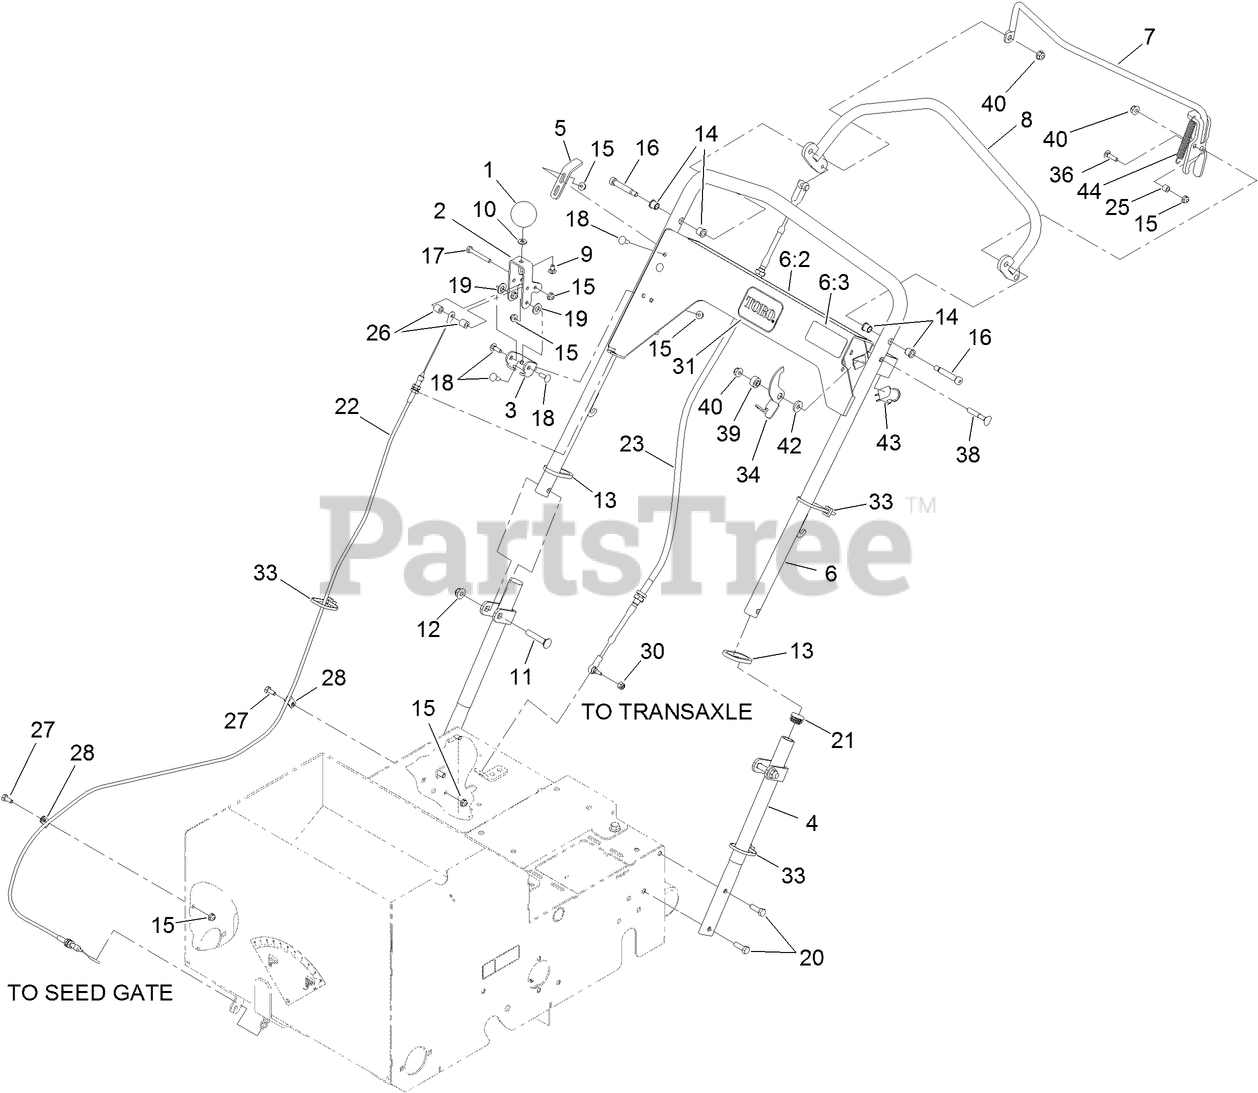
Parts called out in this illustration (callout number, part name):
1	KNOB-RATE, FLOW
2	LEVER-ADJUST, FLOW
3	BRACKET-ADJUST, FLOW
4	HANDLE-LOWER
5	BRACKET-ADJUST, DRIVE
6	HANDLE
6:2	DECAL-CONTROL PANEL, SEEDER
6:3	DECAL-SAFETY LATCH
8	HANDLE-DRIVE
9	SCREW-CARR
10	WASHER-FLAT
11	SCREW-CARR
12	NUT-HF, NI
13	RING-HANDLE LOCK
14	BEARING
15	NUT-HF
16	SCREW-SHOULDER
17	SCREW-HH
18	BOLT-CARR
19	WASHER-PLAIN
20	SCREW-HH
22	CABLE-FLOW, SEED
23	CABLE-PUSH PULL
25	SPACER
26	SPACER
27	SCREW-HH
28	CLAMP-R
30	NUT-LOCK
31	DECAL
33	TIE-CABLE
34	LATCH-BAIL
36	SCREW-CARR
38	SCREW-HANDLE
39	BUSHING-STEPPED
40	NUT-HF, NI
42	WASHER-FLAT
43	SWITCH-BAIL
44	SPRING
